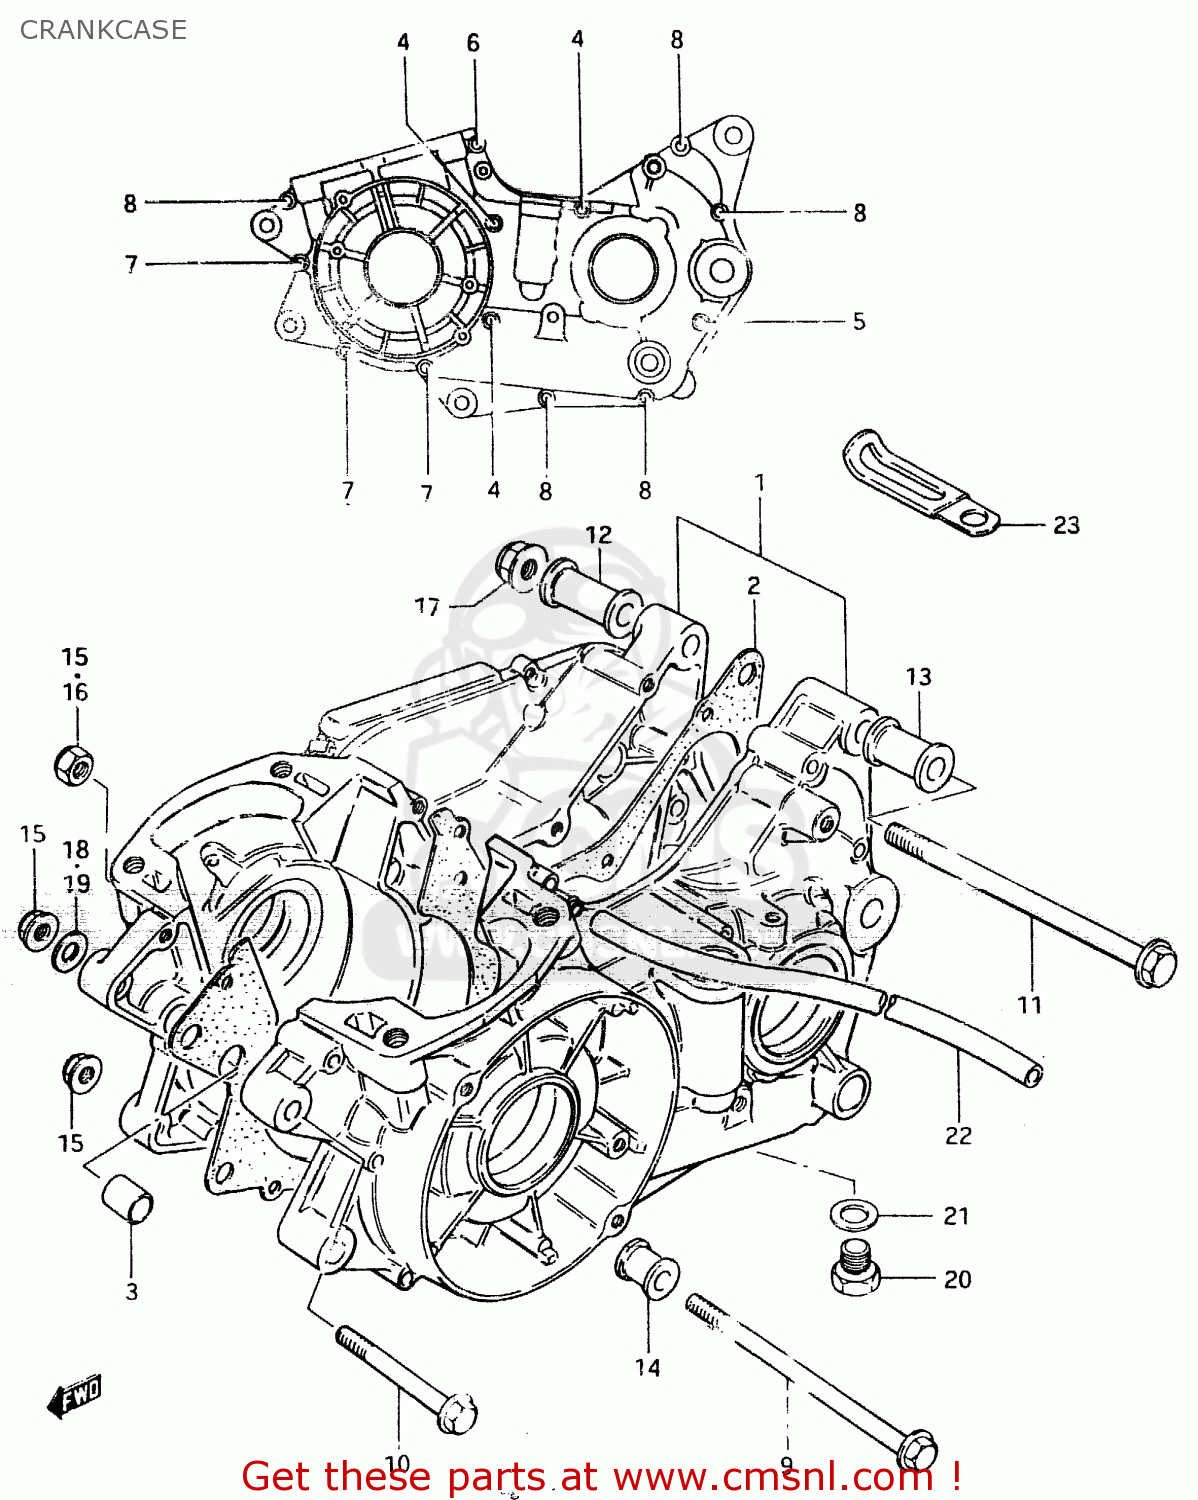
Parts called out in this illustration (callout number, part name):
1	CRANKCASE SET
2	GASKET,CRANKCASE
3	PIN
4	SCREW 6X65
5	SCREW
6	SCREW (6X45)
7	SCREW
8	SCREW (6X35)
9	BOLT 8X200
10	BOLT(8X75)
11	BOLT 10X215
12	SPACER,ENGINE MOUNT
13	SPACER,ENGINE MOUNT
14	SPACER,ENGINE MOUNT
15	NUT
16	NUT
17	NUT
18	WASHER
19	WASHER
20	PLUG
21	GASKET(14X19.2X2) (NAS)
22	HOSE
23	CLAMP
